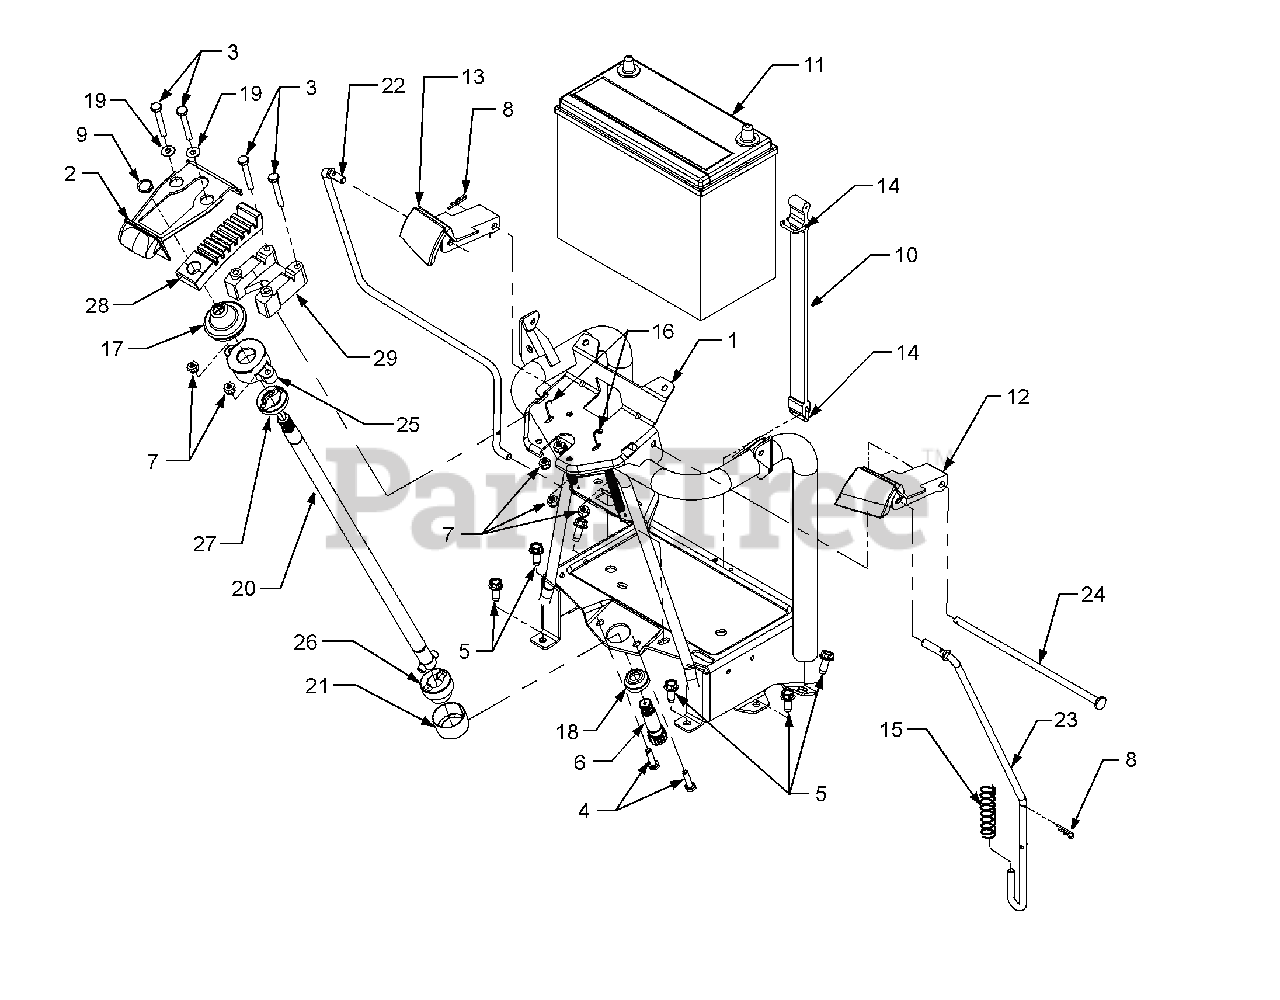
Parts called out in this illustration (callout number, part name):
3	Screw, Hex Cap 1/4-20 x 1.75 GR5
4	Screw, Hex Cap 1/4-20 x 1.0 GR5
5	Screw, Hex Wash. Hd. Tapp 5/16-18 x .75
6	Shaft, Lower Steering
7	Nut, Hex Insert Lock, 1/4-20
8	Pin, Internal Cotter
9	Ring, Retaining, .56 Dia Shaft
10	Strap, Battery
11	Battery
12	Lever, Park Brake
13	Lever, Cruise
14	Hook, Wire Rectangular
15	Spring, Compression, .676 x 2.57
16	Spring, Extension
17	Boot, Tilt Wheel Coupling
18	Boot, Shaft Cover
19	Washer, Flat, .271 x .63 x .065
20	Shaft, Upper Steering
21	Bearing, Sleeve, 1.44 x 1.5 x .812
22	Rod, Cruise Control
23	Rod, Parking Brake
24	Rod, Cruise/Brake Pivot
25	Housing, Tilt Wheel Coupling
26	Coupling Half, Bottom
27	Coupling Half, Top
28	Index, Tilt Steering
29	Block, Tilt Steering
